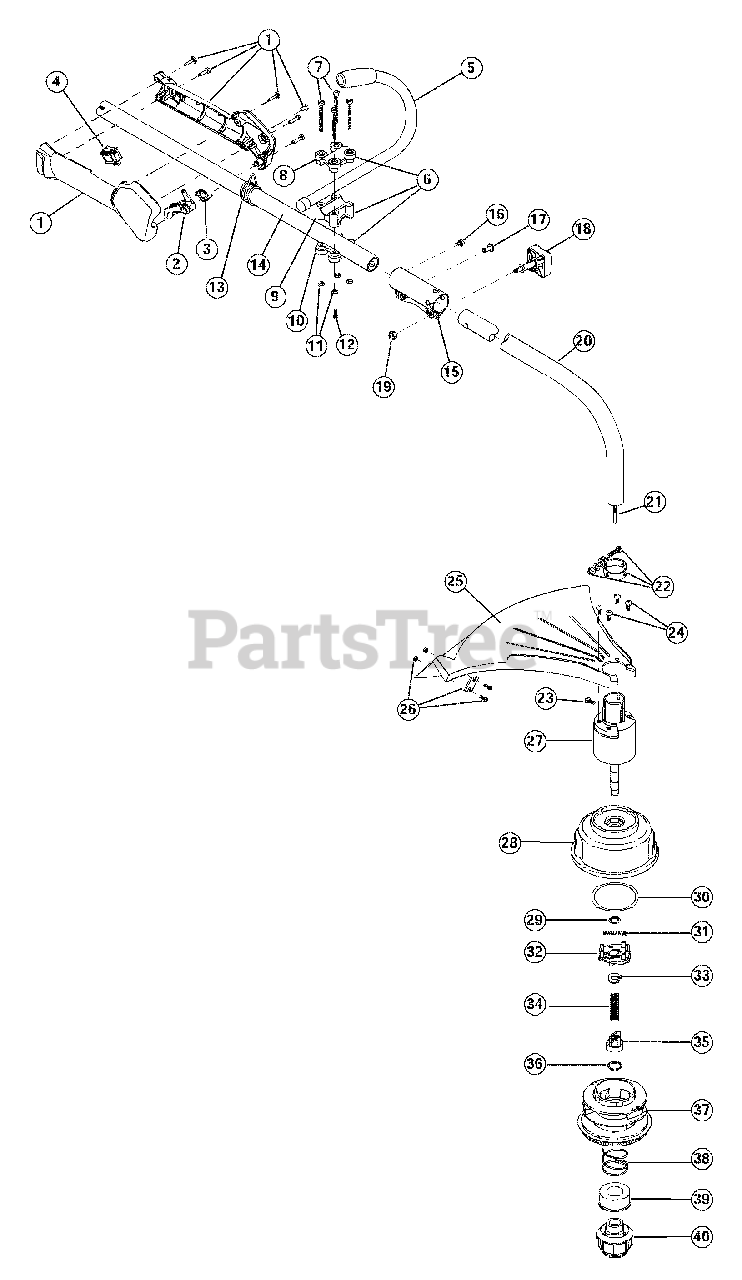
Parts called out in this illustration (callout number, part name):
1	Throttle Housing Assembly (includes 2-4)
2	Throttle Trigger
3	Throttle Trigger Spring
4	Switch Assembly
5	J-Handle Assembly
6	Handle Bracket Assembly (includes 7-12)
8	Upper Handle Clamp
9	Middle Handle Clamp
10	Lower Handle Clamp
12	Anti-Rotation Screw
13	Harness Clip
14	Upper Drive Shaft Housing Assembly
15	Split Boom Coupler (includes 16-19)
18	Adjustment Knob (includes 19)
19	Knob Retaining Nut
20	Lower Drive Shaft Housing Assembly
21	Lower Flexible Drive Shaft
22	Lower Clamp Assembly
23	Anti-Rotation Screw
24	Shield Mounting Hardware
25	Shield Assembly (includes 26)
26	Blade Assembly
27	Bushing Housing Assembly
28	Outer Spool Assembly (includes 29)
29	Retaining Ring
30	Thrust Washer
31	Small Spring
37	Inner Reel
38	Large Spring
40	Bump Head Knob Assembly (includes 38 & 39)
